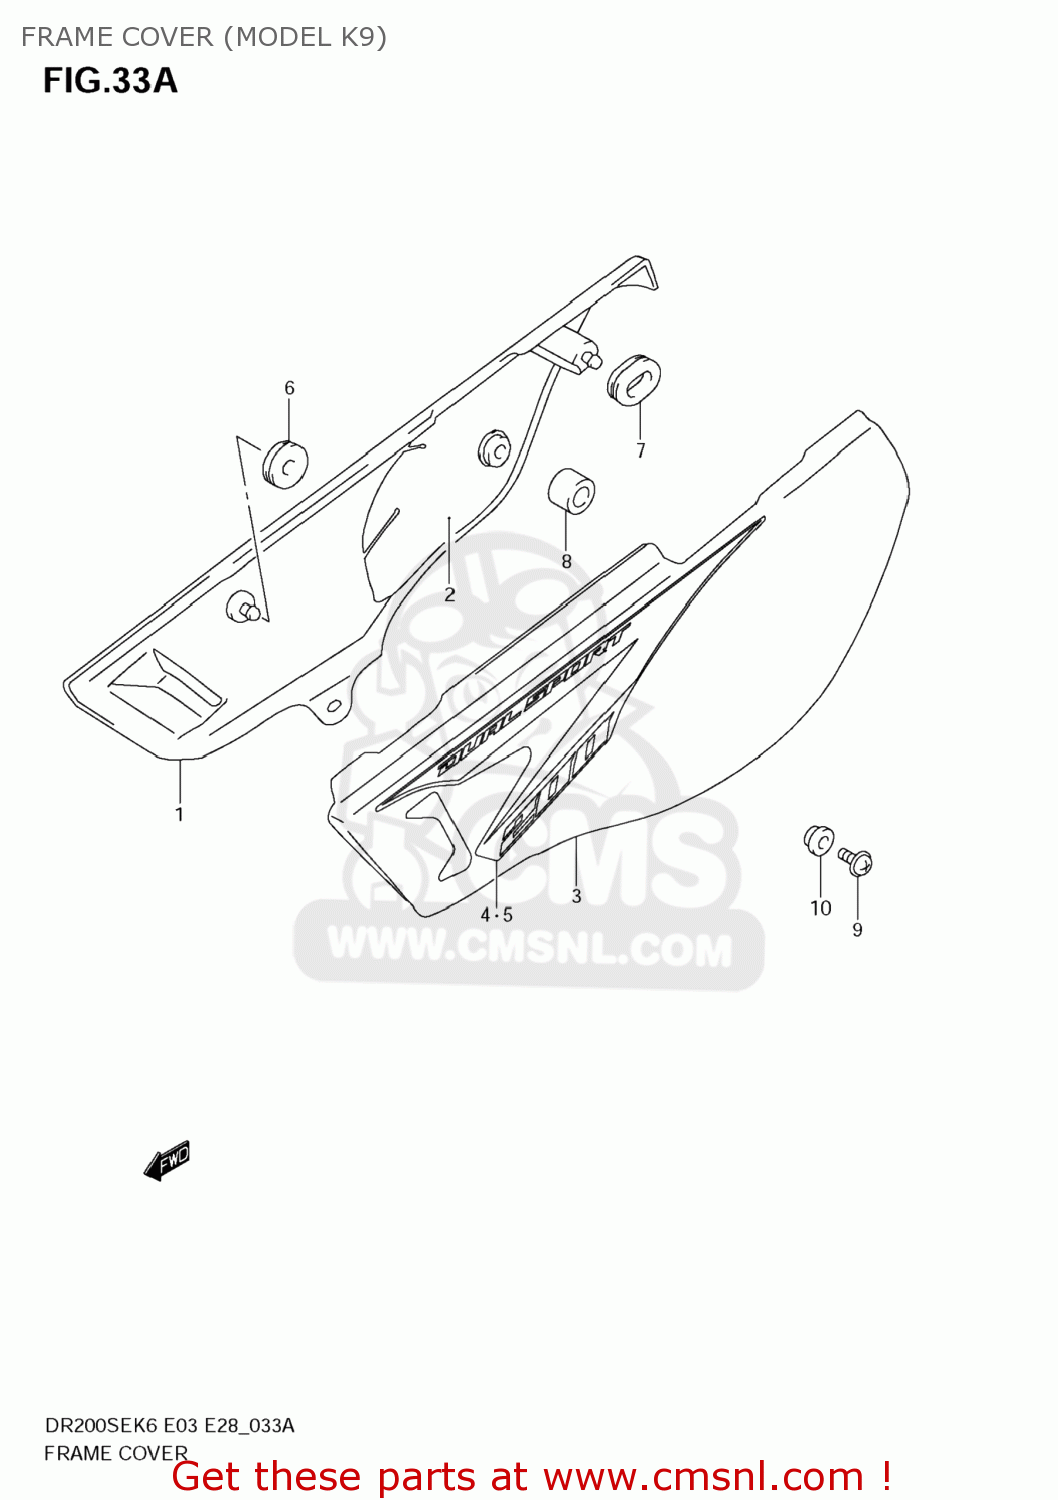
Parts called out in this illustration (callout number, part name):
1	COVER,FRAME,R(BLACK)
2	SHIELD,FRAME COVER,R
3	COVER,FRAME,L(BLACK)
4	TAPE,FRAME COVER,R
5	TAPE,FRAME COVER,L
6	CUSHION
7	CUSHION
8	CUSHION
9	SCREW(6X16)
10	WASHER
